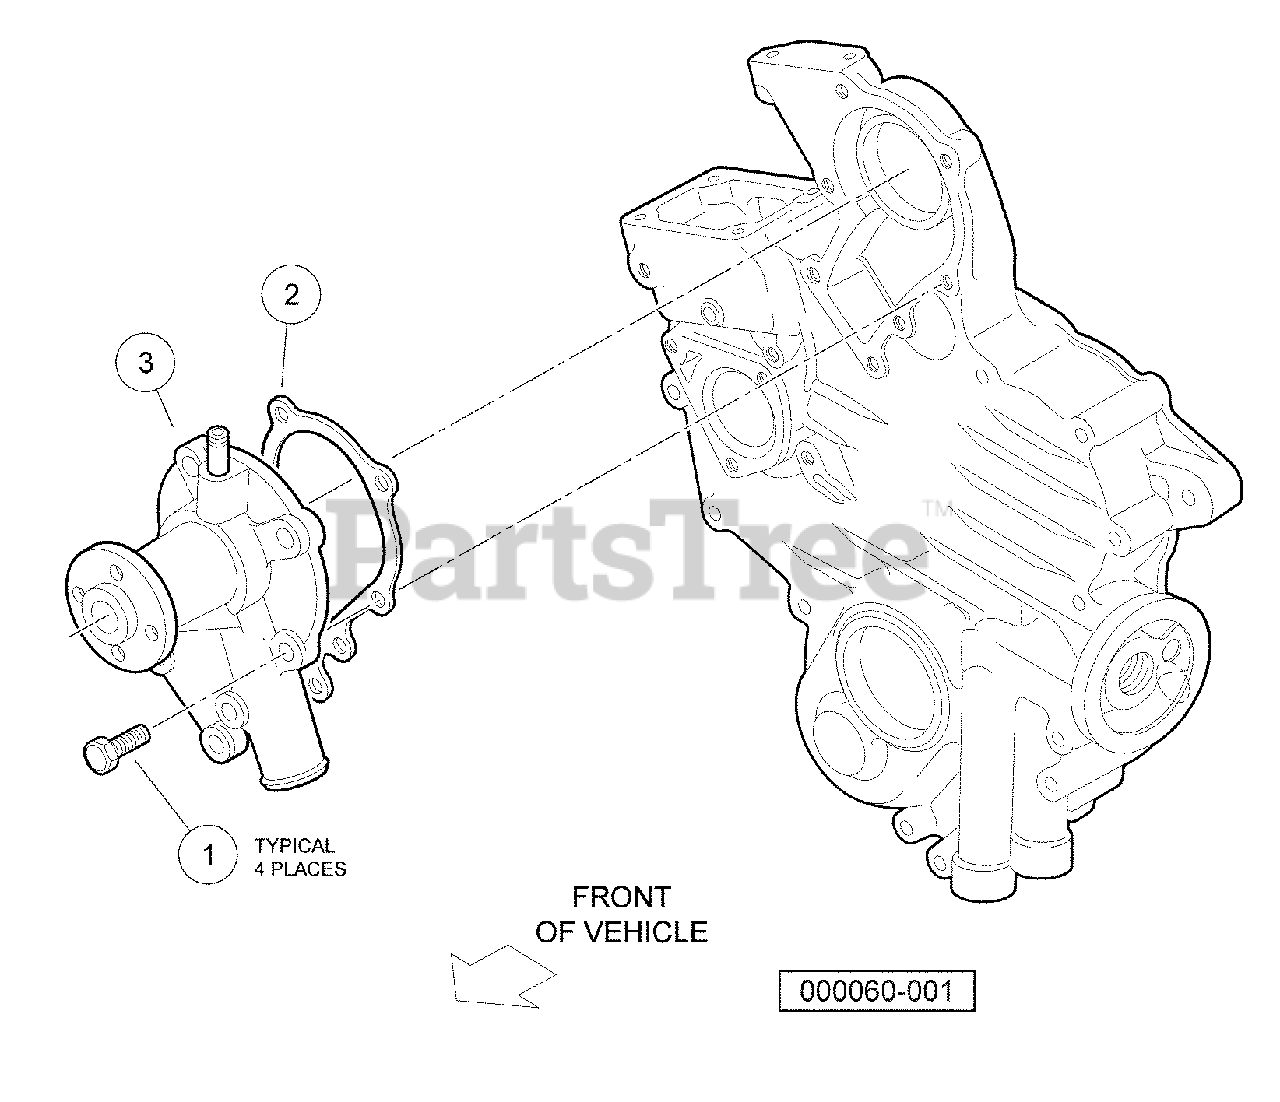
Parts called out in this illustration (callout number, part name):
1	Bolt, M6 X 1 X 22
2	Gasket, Water Pump, D722
3	Water Pump Assembly
